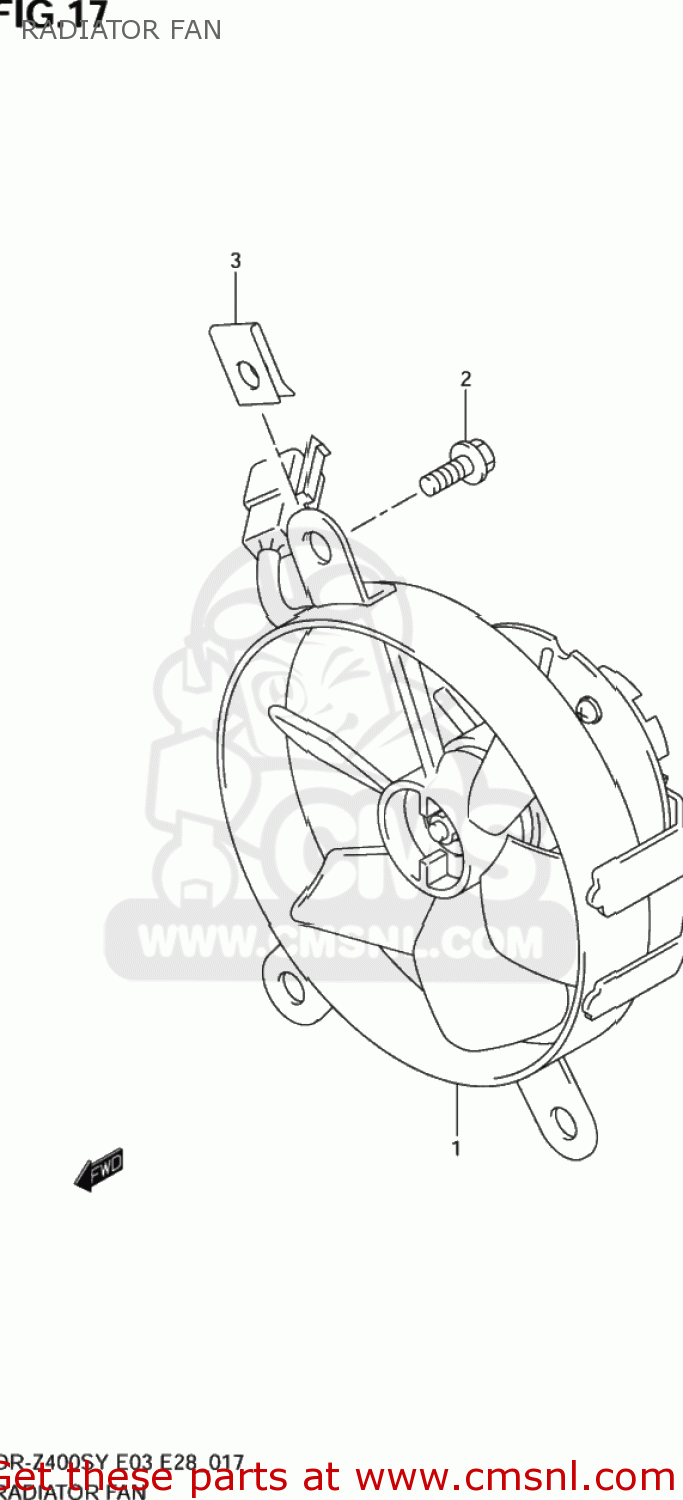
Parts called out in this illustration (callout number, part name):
1	FAN ASSEMBLY,RADIATOR
2	BOLT
3	NUT
